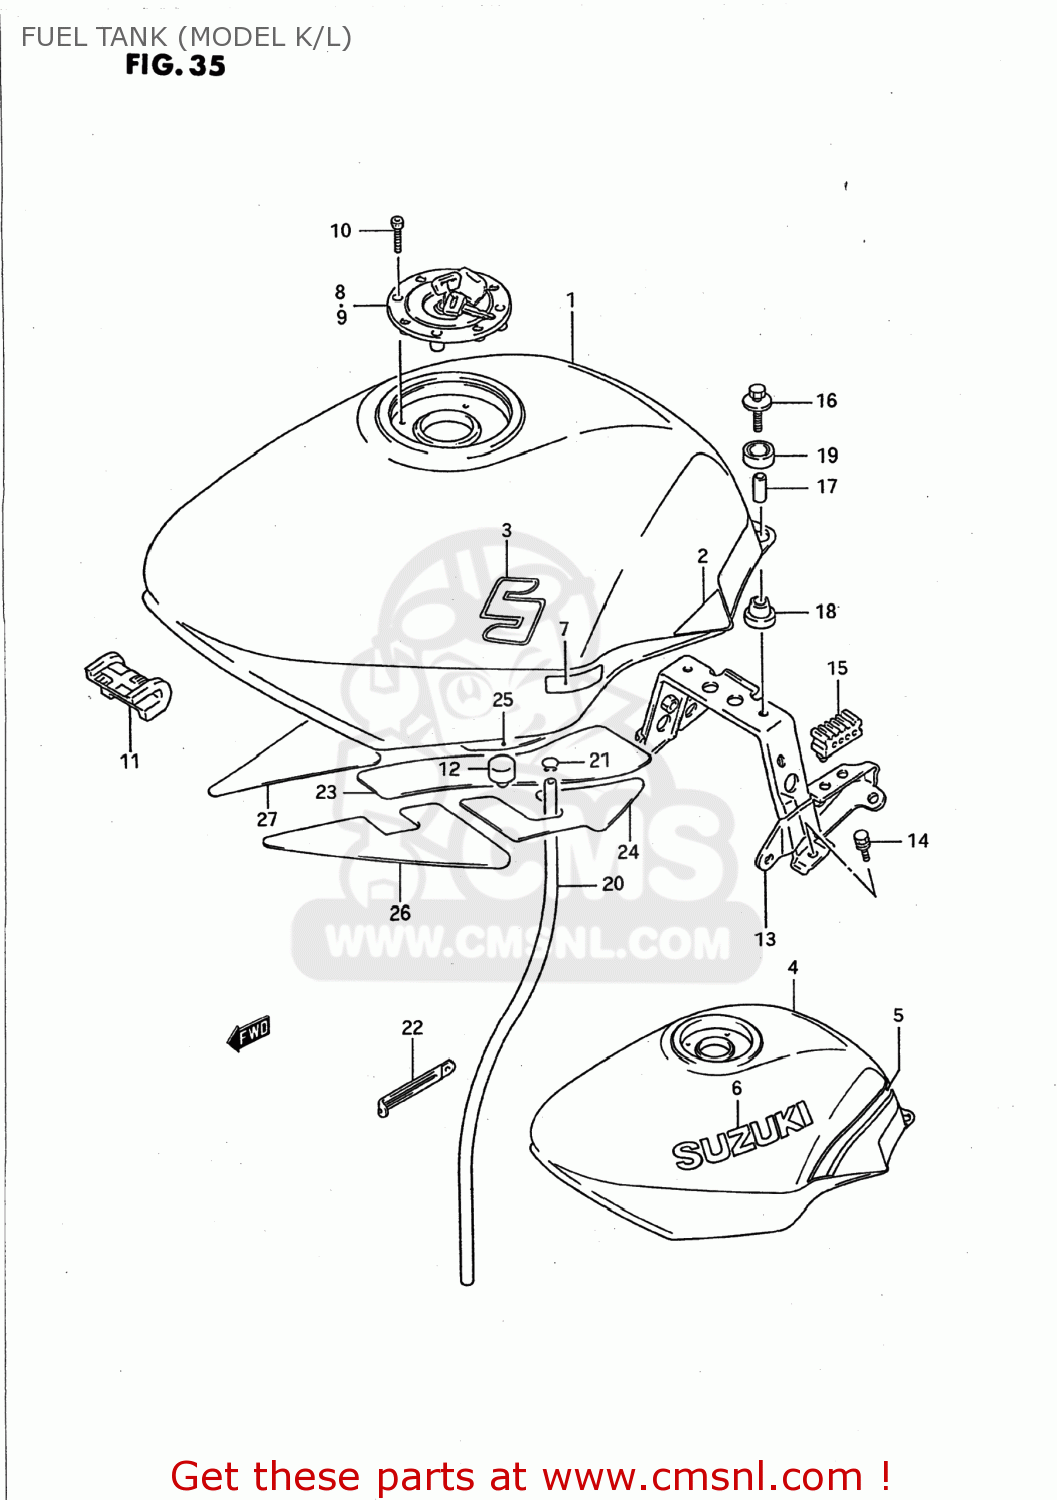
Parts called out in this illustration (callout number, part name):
1	TANK ASSEMBLY,FUEL
2	TAPE SET,FUEL TANK
3	EMBLEM
4	TANK ASSEMBLY,FUEL
5	TAPE,FUEL TANK
6	EMBLEM
7	PROTECTOR,FUEL TANK,LEFT
8	CAP SET,FUEL TANK
9	CAP SET,FUEL TANK
10	BOLT(5X20)
11	CUSHION,FUEL TANK FR
12	CUSHION
13	BRACKET,FUEL TANK RR
14	SCREW
15	CUSHION,SEAT(40X20X15)
16	BOLT
17	SPACER
18	CUSHION
19	CUSHION
20	HOSE,FUEL TANK WATER DRAIN
21	CLIP
22	CLAMP(L:120 T:1.0)
23	HEATSHIELD,CTR
24	HEATSHIELD,RR,L
25	HEATSHIELD,RR,R
26	HEATSHIELD,FR,L
27	HEATSHIELD,FR,R
